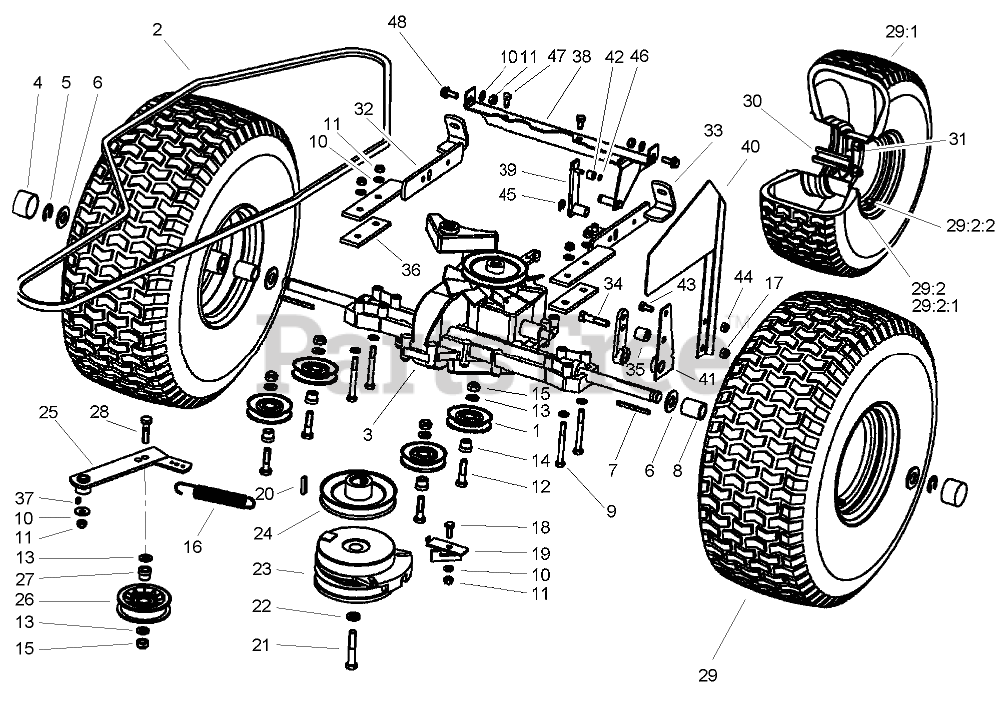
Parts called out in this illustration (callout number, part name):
1	PULLEY-IDLER
2	V-BELT-TRACTION
3	TRANSMISSION
4	CAP-HUB
5	CLIP-SPRING
6	WASHER
7	KEY-SQUARE
8	SPACER-AXLE
9	SCREW-HH
10	WASHER-PLAIN
11	NUT-LOCK, NI
12	SCREW-HH
13	WASHER-FLAT
14	BUSHING-IDLER
15	NUT-LOCK, NI
16	SPRING
17	NUT-LOCK, NI
18	SCREW-HH
19	RETAINER
20	KEY-SQUARE
21	SCREW-HH
22	WASHER-SPRING, BELLEVILLE
23	CLUTCH-ELECTRIC
24	PULLEY-ENGINE
25	ARM-IDLER
26	PULLEY-IDLER
27	BUSHING-IDLER
28	SCREW-HH
29	TIRE AND WHEEL ASM
29:2	WHEEL ASM
29:2:1	RIM
29:2:2	Valve-Tire
30	HUB-WHEEL
31	NUT-WHEEL
32	Bracket-Right
33	Bracket-Left
34	SCREW-HH
35	SLEEVE
36	Plate-Reinforcing
37	FITTING-GREASE
38	Bar ASM
39	Arm-Switch
40	ARM-CONTROL, CRUISE
42	Roller
43	SCREW-HH
44	NUT-LOCK, NI
45	Stirrup
46	STIRRUP
47	SCREW-THREAD FORMING
48	SCREW-HEX
